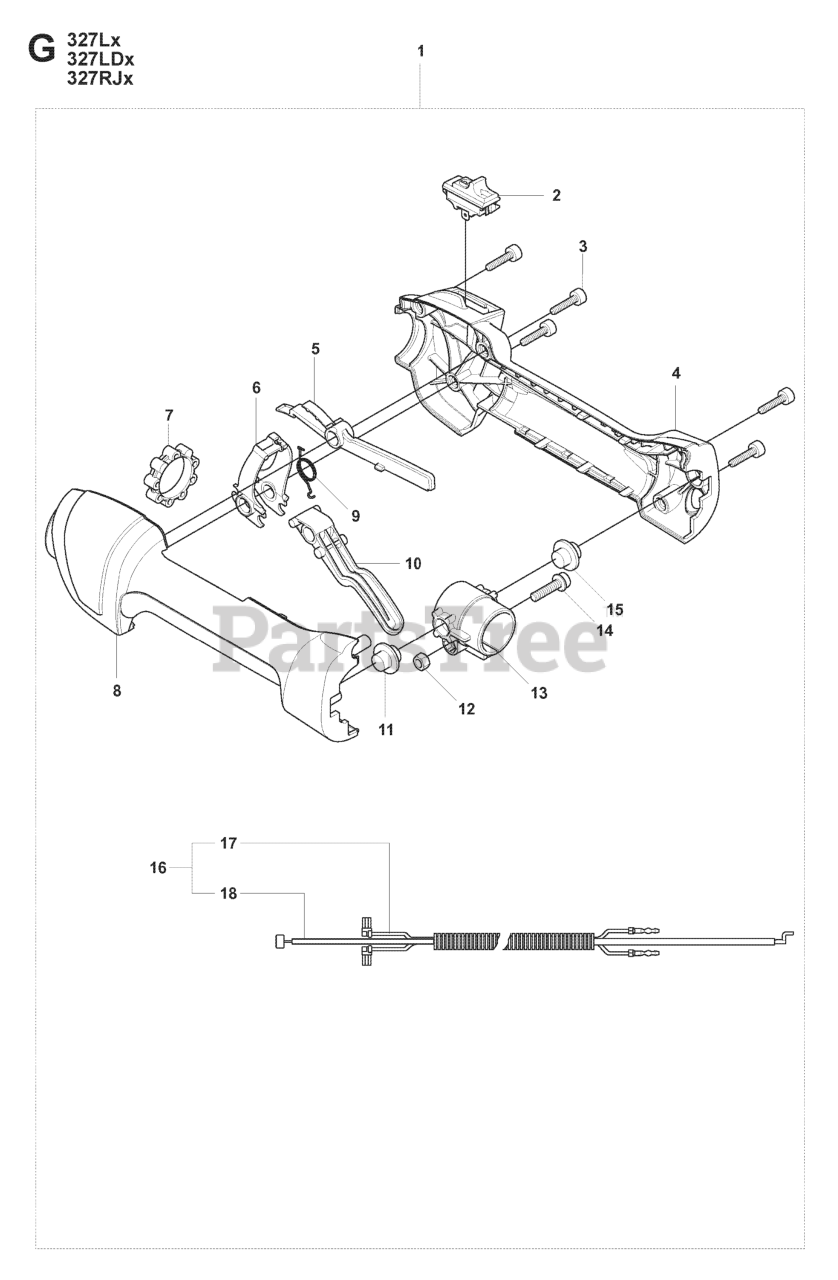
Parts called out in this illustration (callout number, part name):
1	ASSY THROTTLE CONTROL
2	STOP BUTTON
5	THROTTLE LOCK
7	VIBRATION DAMPER
9	RETURN SPRING
10	THROTTLE TRIGGER
11	VIBRATION ABSORBER
15	VIBRATION ABSORBER
17	SHORT CIRCUIT CABLE
18	THROTTLE WIRE ASSY
